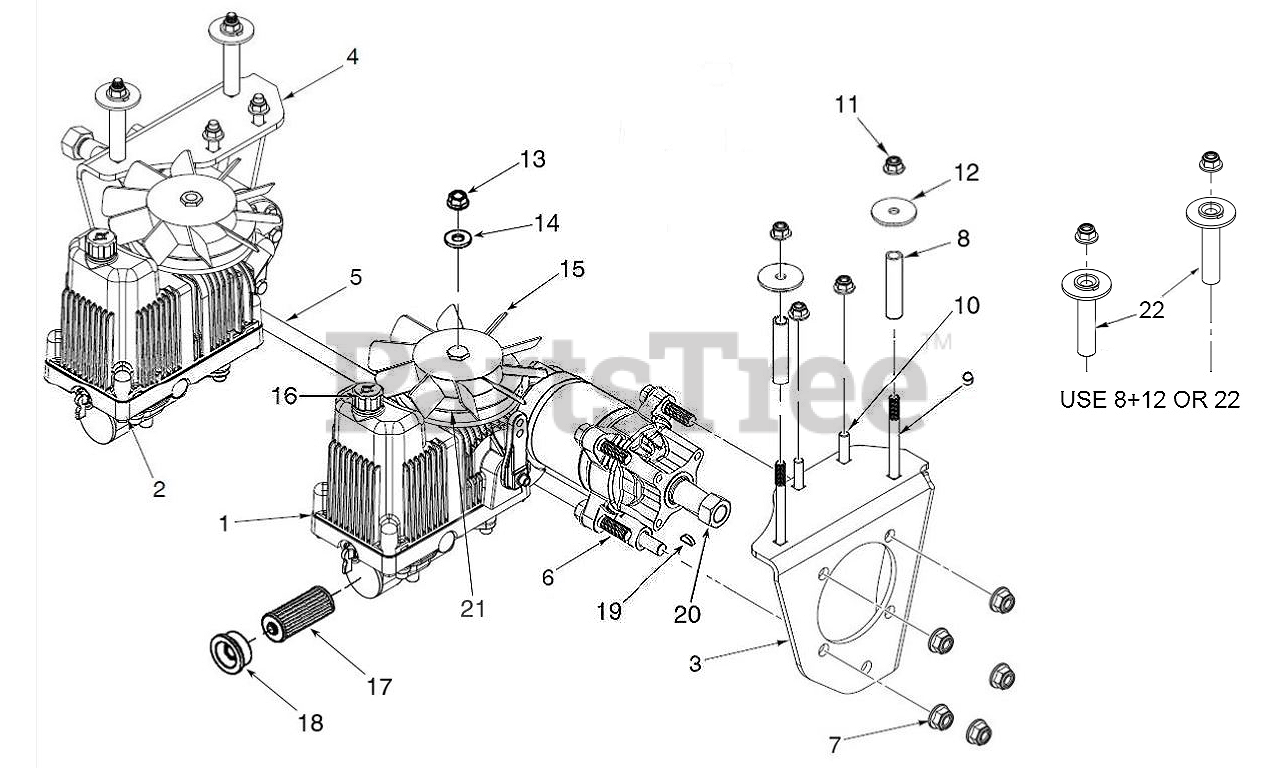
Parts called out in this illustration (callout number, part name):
1	Transmissions
2	Transmissions
6	Screws
7	NUT 1/2-13 HEX FLANGE NYLOK CL
9	RHSNB 3/8-16 X 4 GR5 ZD
10	GSPW Bolts
11	GSPW Nuts
13	Retainers
14	Retainers
17	Filters
20	Axles
